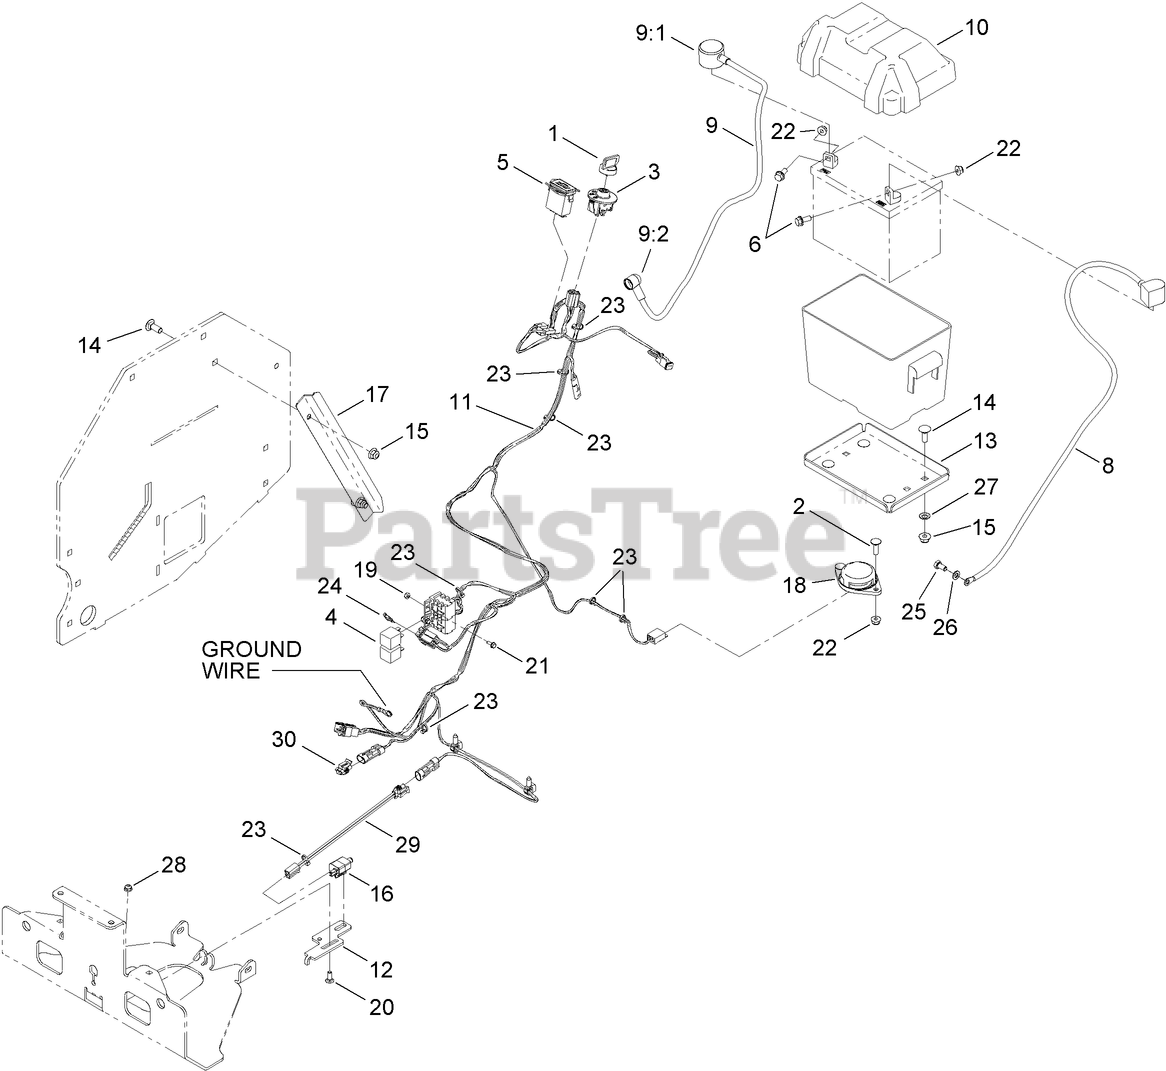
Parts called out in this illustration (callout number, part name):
1	KEYS-IGNITION (SPARE PAIR)
1	KEY-IGNITION
2	BOLT-CARR
3	SWITCH-IGNITION
5	METER-HOUR
6	SCREW-HHF
8	CABLE-BATTERY, BLACK
9	POSITIVE BATTERY CABLE ASM
9:1	INSULATOR-BATTERY
9:2	INSULATOR-SOLENOID
10	BATTERY BOX ASM
11	HARNESS ASM
12	MOUNT-SWITCH
13	TRAY-BATTERY
14	BOLT-CARR
15	NUT-HF, NI
16	SWITCH
17	GUARD-HARNESS
18	SWITCH-SEAT
19	NUT-LOCK, NI
20	BOLT-CARR
21	SCREW-HWH
22	NUT-HF, NI
23	TIE-CABLE
24	FUSE-BLADE TYPE, 20 AMP
25	SCREW-HH
26	WASHER-PLAIN
27	NUT-PUSH
28	NUT-HF
29	JUMPER-SWITCH
30	PLUG-SWITCH, NEUTRAL
